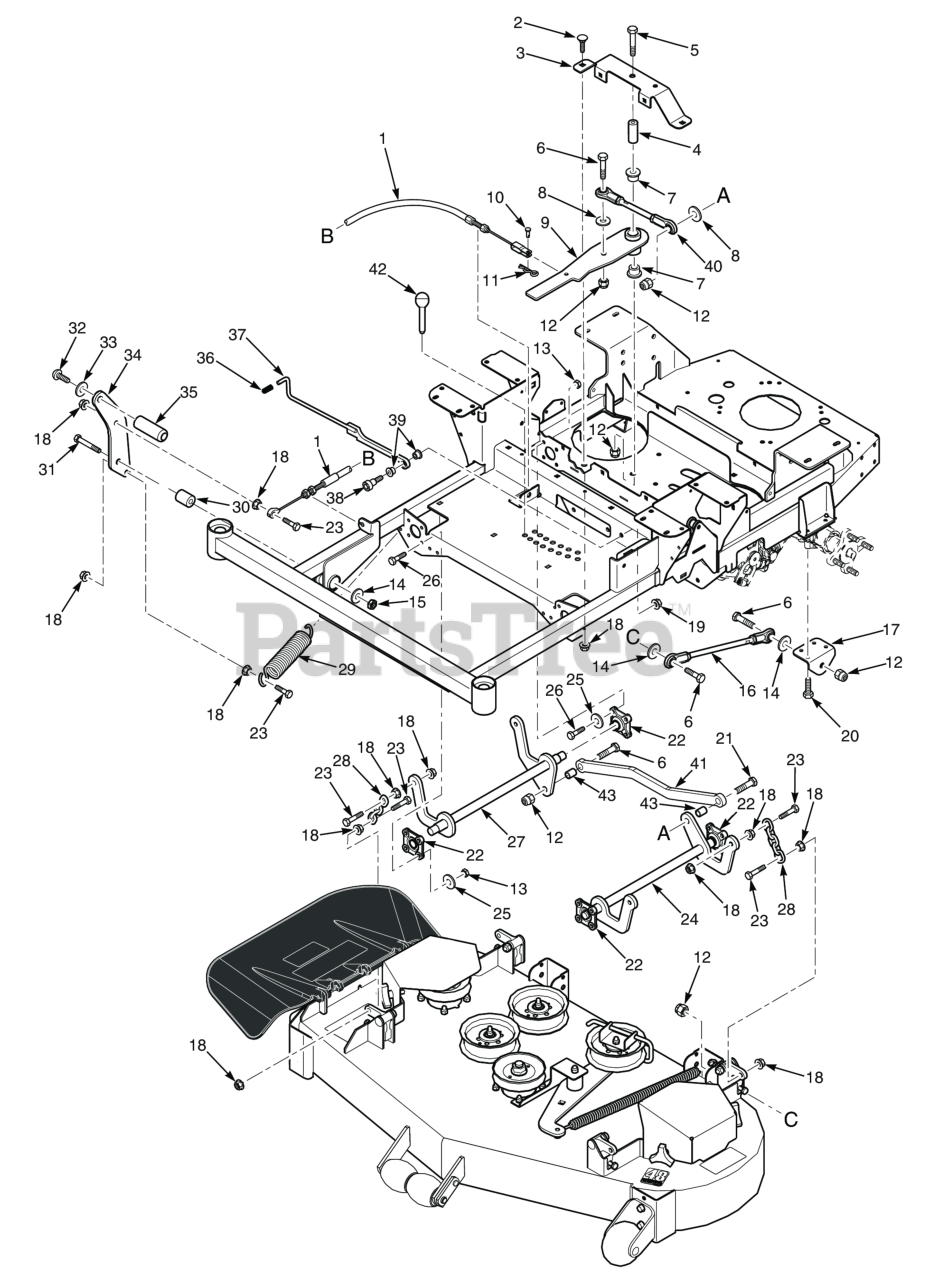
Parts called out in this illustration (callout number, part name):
1	Cable, Deck Lift
2	Bolt, Carriage 3/8-16 x 3/4"
3	Support, Idler Arm
4	Spacer, Deck Lift Pivot
5	Bolt, Hex Head, 1/2-13 x 3-1/4"
6	Hex Head Bolt, 1/2-13 x 2"
7	Bearing, Plastic
8	Flatwasher, 1/2 - .531 x 1.062 x .095
9	DECKLIFT BELLCRANK ASSY, SFZ
10	Clevis Pin, 5/16 x 3/4"
11	COTTER PIN, HAIR - 0.94 X 1.62
12	HEX LOCKNUT, ELASTIC STOP, 1/2-13
13	HEX NUT, ELASTIC STOP LOCK, 5/16-18
14	Flat Washer, 1/2 (.562 x 1.375 x .109)
15	HEX NUT, ELASTIC STOP LOCK, 3/8-16
16	Linkage, Push Arm
17	Bracket, Push Arm Link
18	NUT, 3/8-16 SERRATED FLANGE HEX HEAD
19	HEX NUT, ELASTIC STOP LOCK, 3/8-16
20	Bolt, Hex Head 5/16-18 x 3.00"
21	Bolt, Hex Head 1/2-13 x 3"
22	Bearing, Deck Lift - 48V & 52V
23	Bolt, Hex Head 3/8-16 x 1-1/2" B&S 32BV
24	Weldment, Deck Lift LH
25	Flatwasher, 1/4" (.312 x .750 x .065")
26	Bolt, Heax Head 5/16-18 x 1" (48V / 52V)
27	Weldment, Deck Lift RH
28	Chain, Deck Lift
29	Spring, Deck Lift
30	Spacer, Deck Lift Pivot
31	Bolt, Hex Head 1/2-13 x 3"
32	Bolt, Head Socket 5/8-11 x 1-1/2"
33	Lockwasher, 5/8" Spring
34	Pedal, Foot Bracket
35	Foot Pedal, Height Adjustment
36	Grip, Deck Latch
37	Weldment, Deck Latch
38	Bolt, Shoulder 1/2 x 1/2"
39	Bearing
40	Linkage Assembly, Deck Lift
41	Mounting Bracket, Fuel Tank Front
42	Pin, Height Adjuster
43	Sleeve
